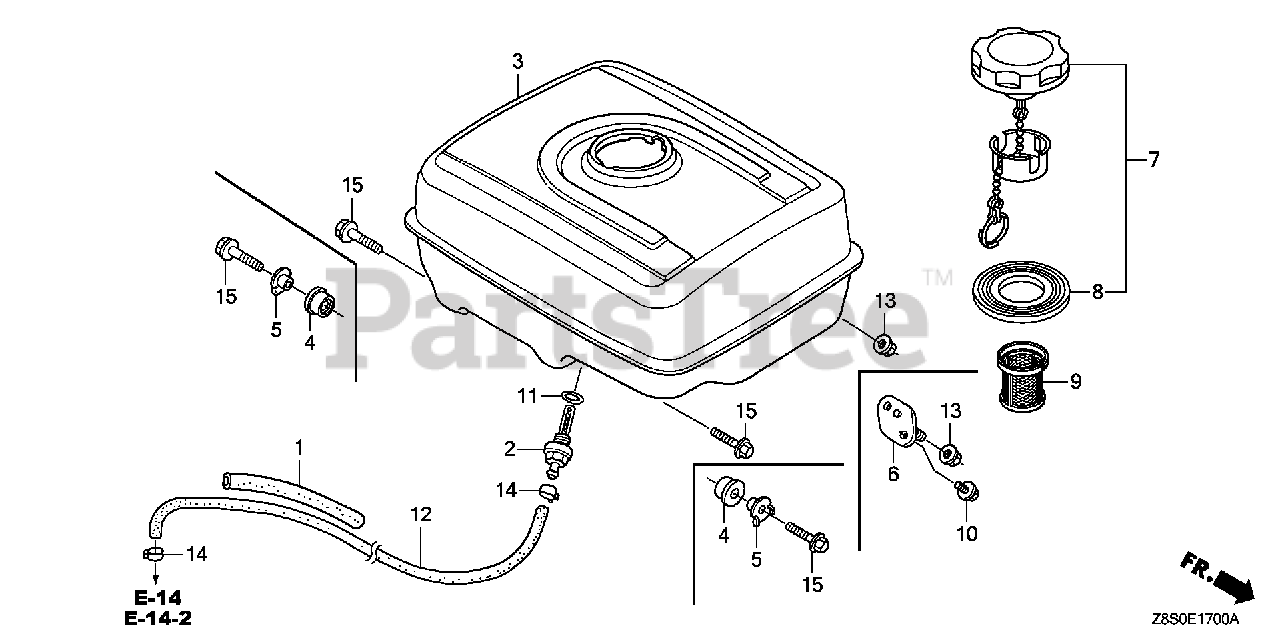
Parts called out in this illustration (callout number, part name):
1	RUBBER, SUPPORTER (107MM)
2	JOINT, FUEL TANK
3	TANK, FUEL *NH1* (BLACK)
3	TANK, FUEL *NH31* (MCKINLEY WHITE)
7	CAP, FUEL FILLER
8	GASKET, FUEL FILLER CAP
8	GASKET, FUEL FILLER CAP (39X62X3) (TOUYOUSYA)
9	FILTER, FUEL (FROM 1204807)
11	O-RING (14MM) (ARAI) Use up to Engine SN 2949254.
11	O-RING (14MM) (NOK)
12	TUBE, FUEL (4.5X210) (FKM)
13	NUT, FLANGE (8MM)
14	CLIP, TUBE (D8)
15	BOLT, FLANGE (8X25)
